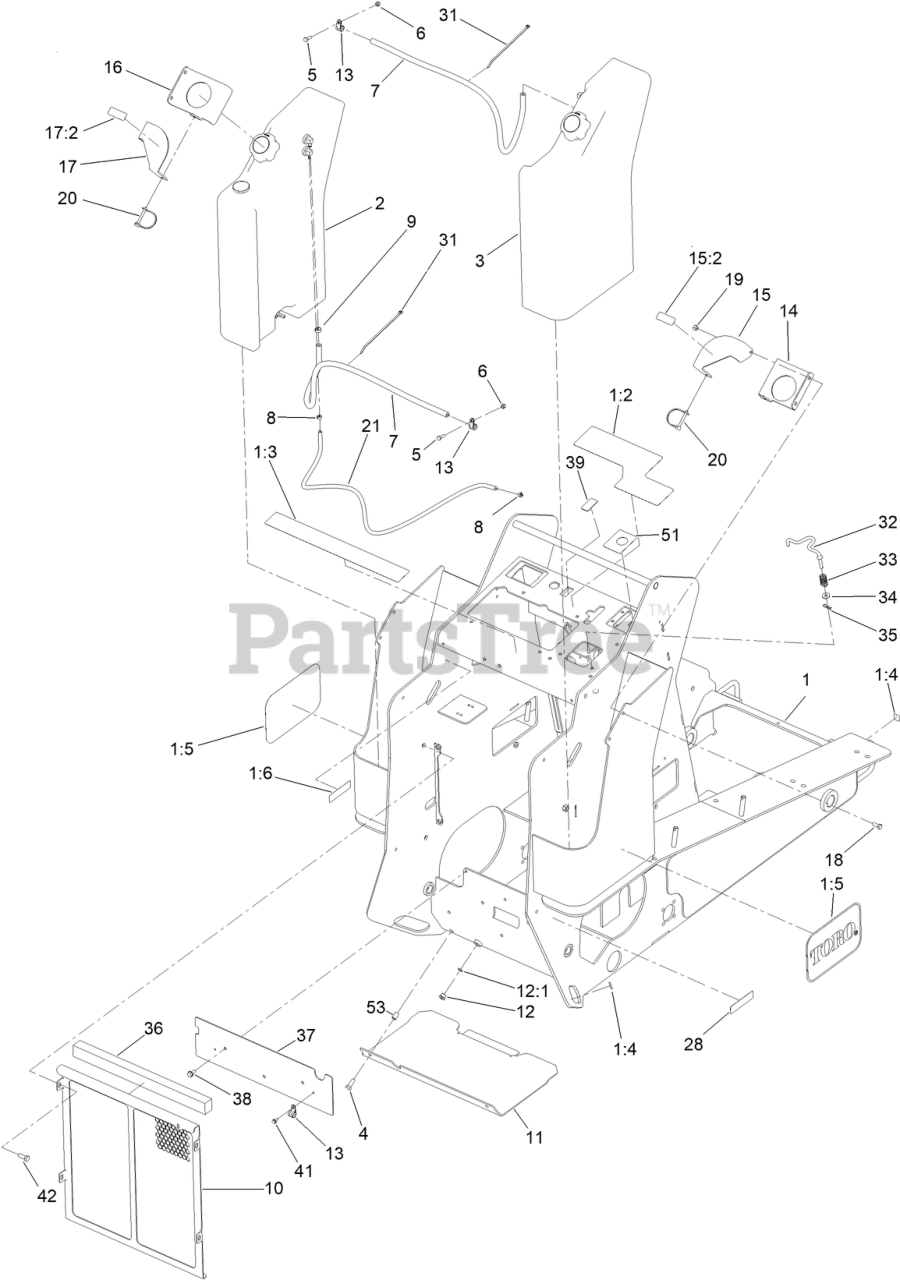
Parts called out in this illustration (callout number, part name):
1	FRAME
1:2	DECAL-CONTROL PANEL
1:3	DECAL-SAFETY
1:4	DECAL-POINT, LIFT
1:5	DECAL
1:6	DECAL-RADIATOR FILL
2	LH FUEL TANK ASM
3	RH FUEL TANK ASM
4	SCREW-HH
5	SCREW-HH
6	NUT-HF
7	HOSE-FUEL
8	CLAMP-HOSE
9	CLAMP-HOSE
10	RADIATOR COVER ASM
11	COVER-BOTTOM
12	PLUG-HEX, HOLLOW
12:1	O-RING
13	CLAMP-R
14	PLATE-HOLD DOWN, RH
15	PLATE-LOCK, FUEL CAP, RH
15:2	DECAL-DIESEL
16	PLATE-HOLD DOWN, LH
17	PLATE-LOCK, FUEL CAP, LH
17:2	DECAL-DIESEL
18	SCREW-HH
19	NUT-LOCK, NI
20	PIN-HITCH
21	HOSE-FUEL
28	DECAL-ARRESTOR, SPARK
31	TIE-CABLE
32	ROD-INTERLOCK
33	SPRING-CONTROL
34	WASHER-FLAT
36	SEAL-FOAM
37	PLATE-COVER
38	SCREW-HWHTF
39	PLUG-HOLE
41	SCREW-HWH
42	SCREW-HH
51	DECAL-IGNITION SWITCH
53	NUT-CLINCH
